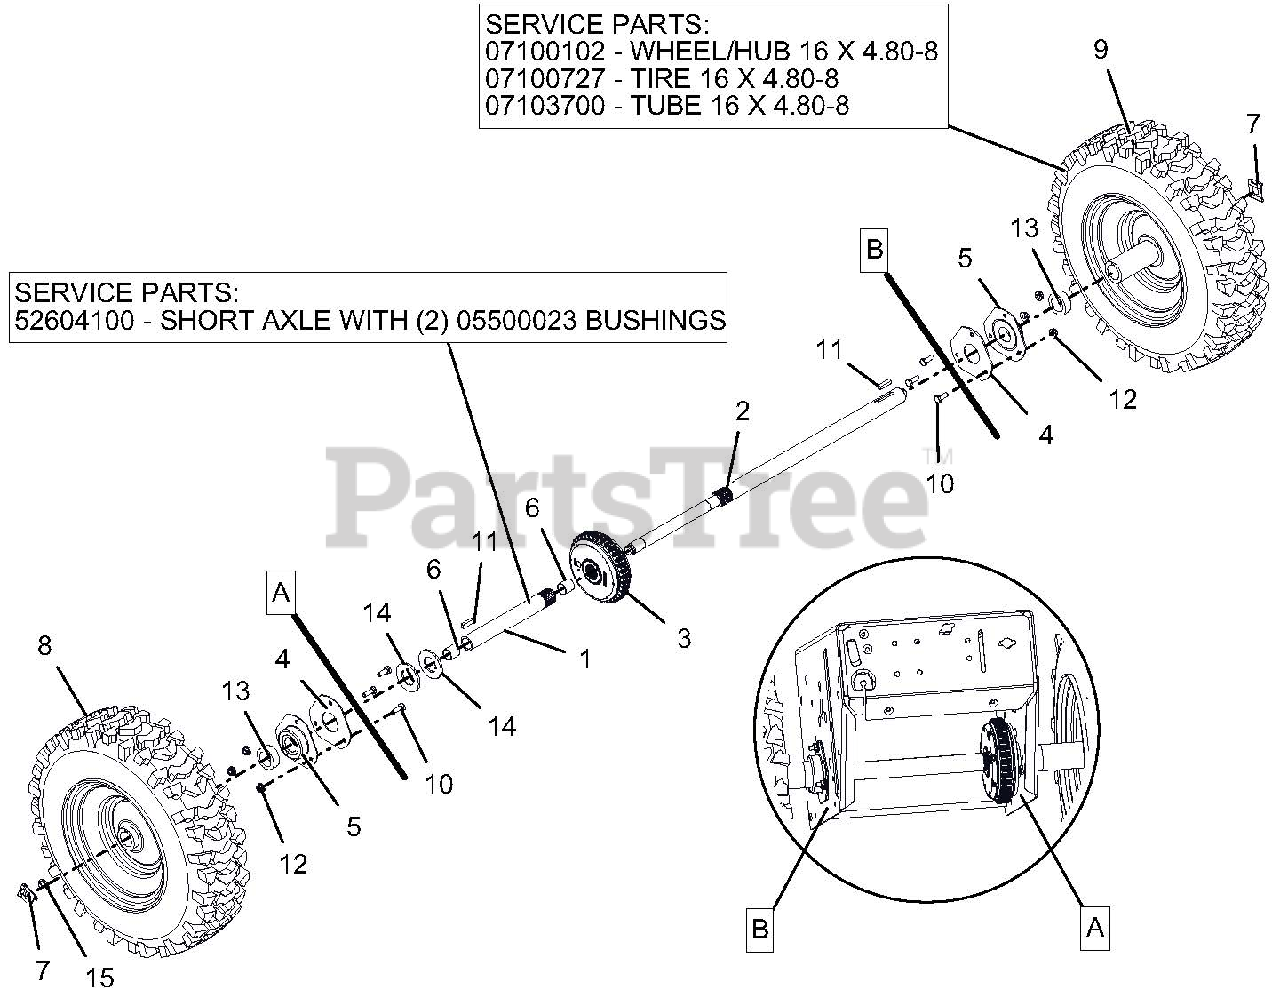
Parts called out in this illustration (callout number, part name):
1	AXLE, SHORT-PRO AUTO DIFF
1	AXLE, SHORT-AUTO W/BUSHINGS
1	BSHG-SLV .706X.764X.75 BRZ
2	AXLE, LONG-PRO AUTO DIFF
3	DIFFERENTIAL, AUTOMATIC
4	PLATE, BEARING SPACER
5	BRG-FLG 1.003/1.000 3 BOLT
6	BSHG-SLV .706X.764X.75 BRZ
7	CLIP, SNAP .625 DIA
8	TIRE/WHEEL,RH 16X4.8-8 DIFF T2
9	TIRE/WHEEL,LH 16X4.8-8 DIFF T2
9	HUB, WHEEL - 16X4.8-8 DIFF
9	TIRE, 4.80-8 K478
9	TUBE
10	@BLT-HEX .25-20X.75 GR5 YWZC
11	KEY-RECT .25X.188X1.00
12	@NUT-LK-CTR-FLG .25-20 YWZC
13	SPACER, PRO AXLE BEARING
14	WSHR-FL-STL- 1.062X2.0X.134 YZ
15	RG-RTNG-EXT .625X.042
